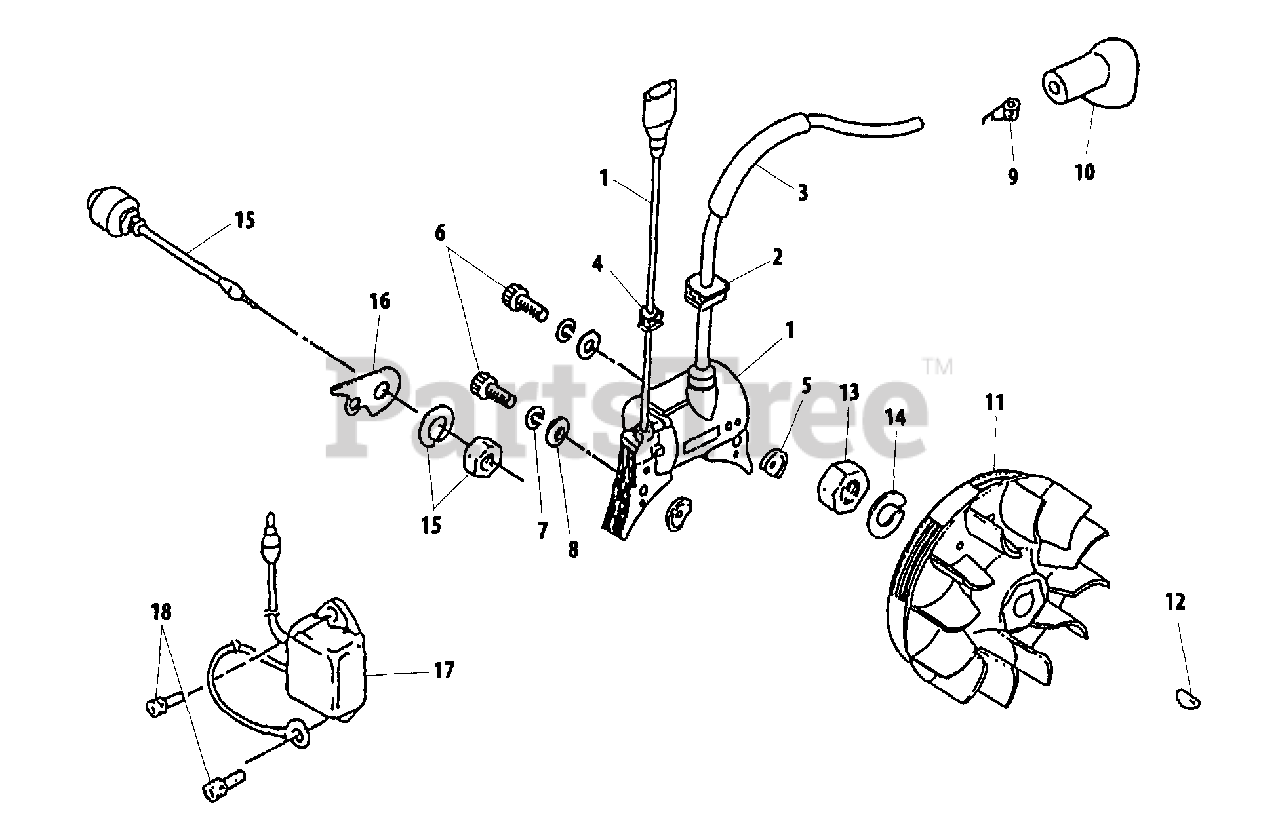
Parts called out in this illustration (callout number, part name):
1	COIL, IGNITION
2	GROMMET
3	TUBE
4	GROMMET
5	INSULATOR
6	SCREW - 4X26
7	LOCKWASHER - 4
8	WASHER
9	TERMINAL, SPARK PLUG CAP
10	CAP, SPARK PLUG
11	FLYWHEEL
12	KEY - 3X10
13	NUT - 10
14	LOCKWASHER - 10
15	SWITCH, IGNITION
16	BRACKET
17	UNIT, ELECTRONIC
18	SCREW - 4X12
